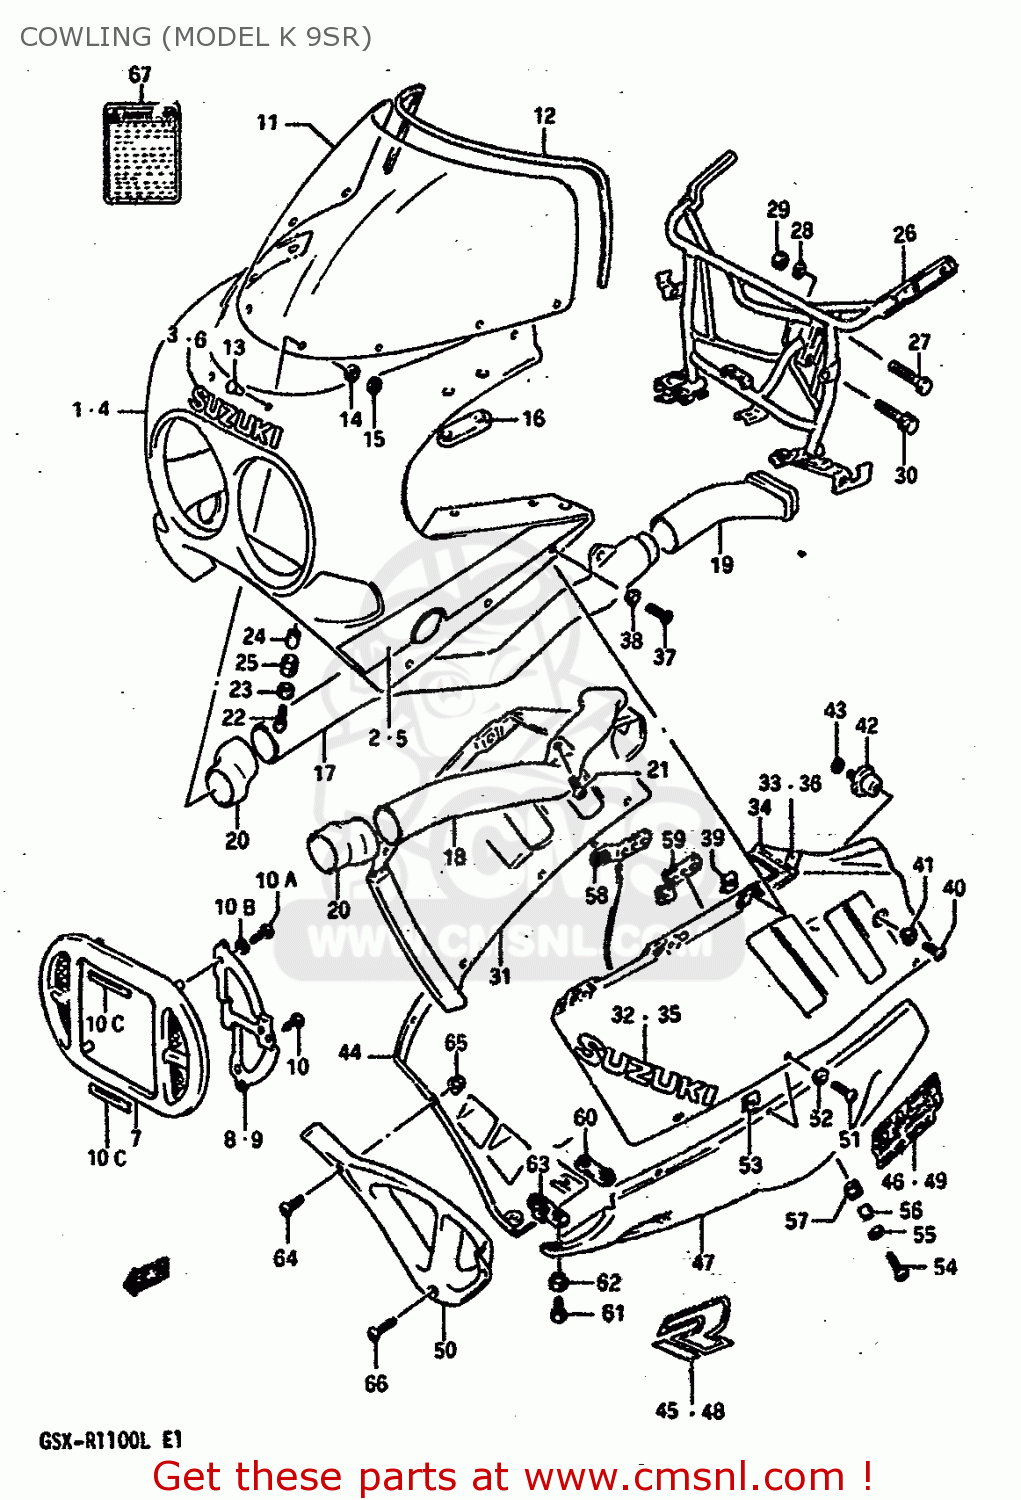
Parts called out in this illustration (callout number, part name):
1	BODY ASSY,COWLING
2	TAPE SET,COWLING,UPPER
3	EMBLEM,COWLING,FRONT
4	BODY ASSY,COWLING (BLUE/WHITE)
5	TAPE SET,COWLING,UPPER
6	EMBLEM,COWLING,FRONT
7	COVER,FRONT (WHITE)
8	PLATE,COVER RH
9	PLATE,COVER LH
10	TAPPING SCREW 4X10/A
10A	SCREW
10B	SPACER
10C	CUSHION
11	SCREEN SET,WIND
12	MOLDING
13	PIN,WINDSCREEN
14	CUSHION
15	NUT
16	CUSHION,RR VIEW MIRRORR
17	PIPE,AIR INTAKE FR,R
18	PIPE,AIR INTAKE,FRONT
19	PIPE,AIR INTAKE RR,R
20	JOINT,AIR INTAKE
21	SCREW, CENTER
22	SCREW(6X20)
23	WASHER(6.5X18X1)
24	SPACER
25	CUSHION
26	BRACE,COWLING
27	BOLT
28	WASHER,LOCK,8.
29	NUT ,8MM
30	BOLT
31	COVER ASSEMBLY,COWLING
32	EMBLEM
33	TAPE,COWLING SIDE,RIGHT
34	COVER COMP,COWLING SIDE,LEFT
35	EMBLEM
36	TAPE,COWLING SIDE,LEFT
37	SCREW(5X18)
38	WASHER(5.2X14X1.5)
39	NUT,HEADLAMP HOUSING,UPPER
40	SCREW(6X12)
41	WASHER(6.3X16X1.5)
42	CUSHION,COWLING
43	WASHER,LOCK
44	COWLING,UNDER,
45	EMBLEM,COWLING UNDER
46	EMBLEM
47	COVER,COWL LH
48	EMBLEM,COWLING UNDER
49	EMBLEM
50	COWLING,UNDER,CENTER
51	SCREW(5X18)
52	WASHER(5.2X14X1.5)
53	NUT,HEADLAMP HOUSING,UPPER
54	SCREW(6X20)
55	WASHER(6.5X18X1)
56	SPACER
57	CUSHION
58	BRACKET
59	BRACE,COWLING UNDER,LH
60	BRACE,COWLING LWR COVER RR
61	SCREW(6X16)
62	WASHER(6.3X16X1.5)
63	BRACE,COWLING LWR COVER
64	SCREW(5X14)
65	NUT
66	SCREW(6X16)
67	LABEL (WARNING)
